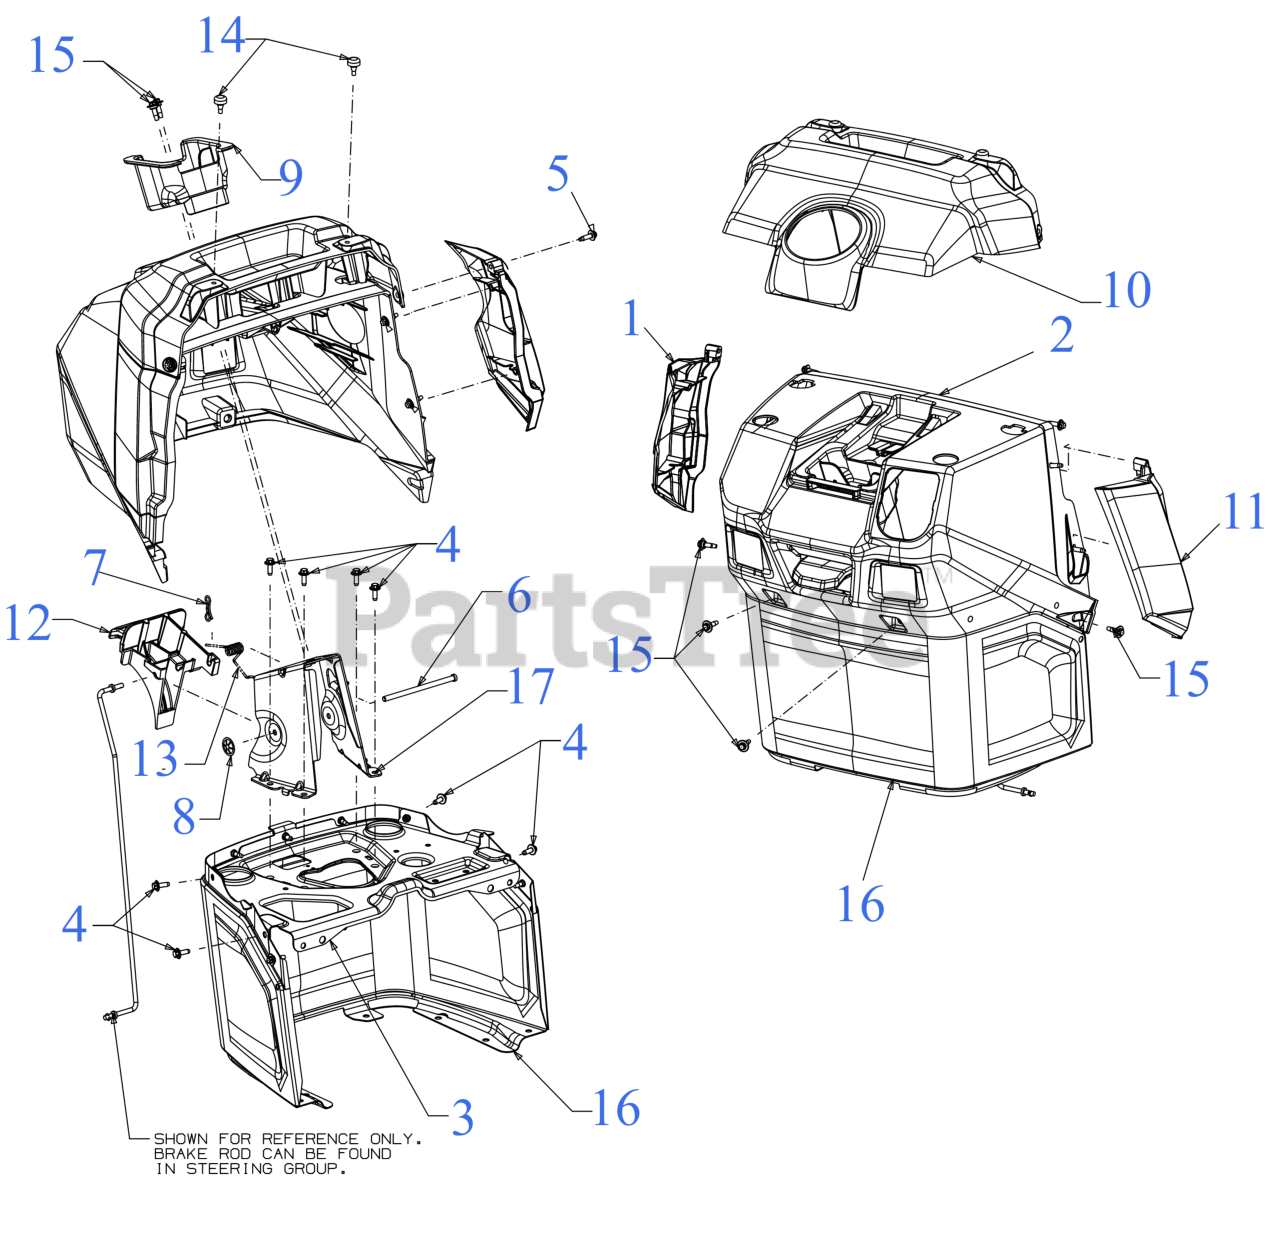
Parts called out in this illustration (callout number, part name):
1	DASH CAP (LH)
2	DASH (UPPER)
3	DASH PLATE (ELECTRIC)
4	SCREW M6-1 x .625
5	SCREW 1/4-10 x .750
6	HINGE PIN .25 x 4.50
7	BOW TIE COTTER PIN 1/4-5/16
8	PUSH ON NUT
9	STEERING SHAFT BEARING
10	UPPER DASH CAP (CRAFTSMAN)
11	DASH SIDE CAP (RH)
12	BRAKE LEVER
13	TORSION SPRING .330 ID
14	BUMPER, .62 DIA x .3
15	SHOULDER SCREW M6-1 .368 X.115
